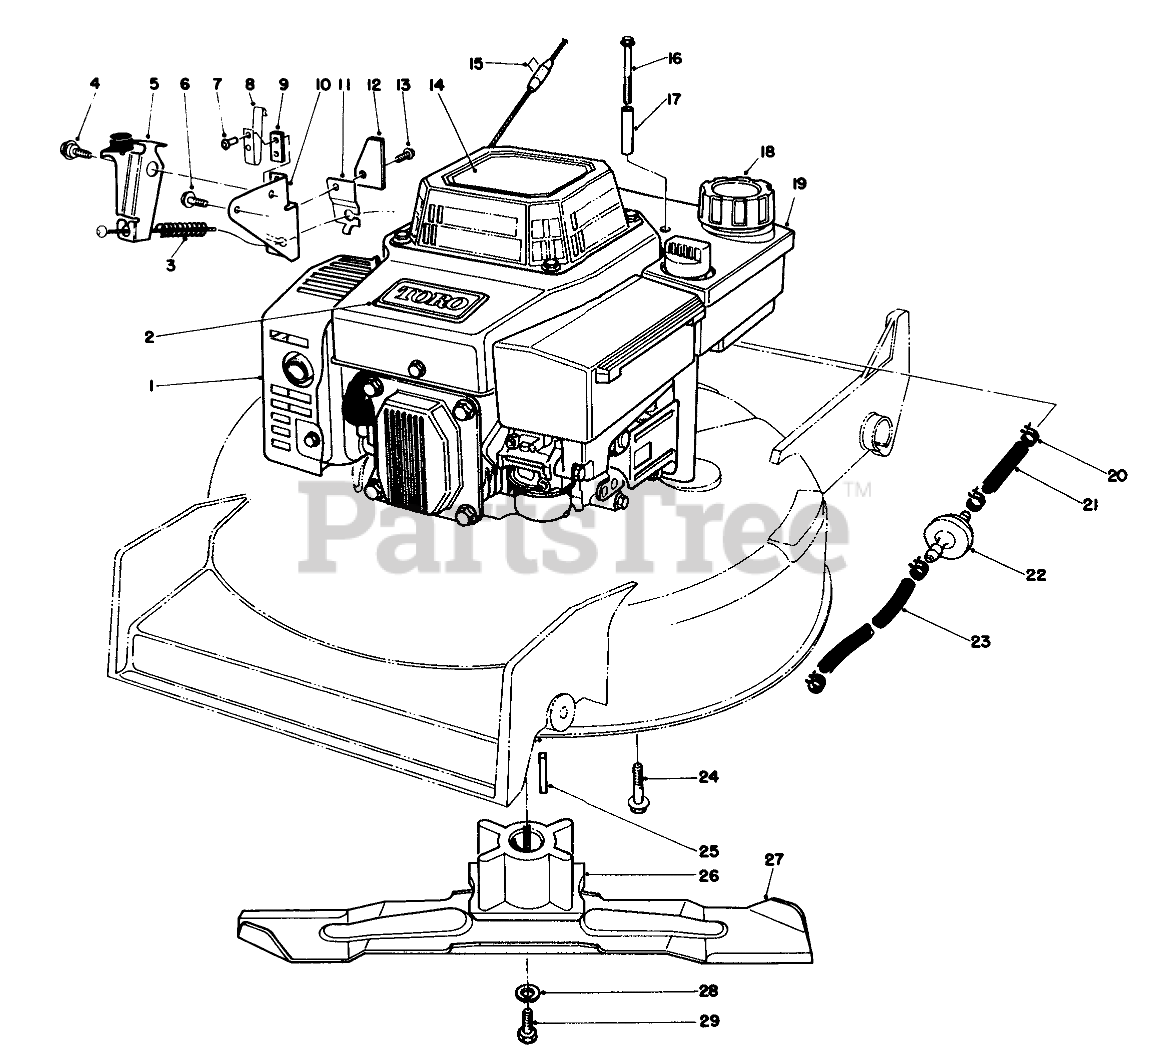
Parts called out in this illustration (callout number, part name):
1	Engine
2	TORO LOGO PLT
3	COMPRESSION SPRING
4	Screw-Shoulder
5	BRAKE PLATE ASM
6	THO FORM SCREW M6 X 1
7	RIVET-PLASTIC
8	Strap-Ground
9	Strap-Insulation
10	Plate-Mounting
11	CABLE CLAMP
12	STOP-GROUND STRAP
13	SCREW
14	OHV RECOIL DECAL
15	STAPLE
16	THRD FORMING SCREW
17	TUBULAR SPACER
18	GAS CAP ASM
19	TANK ASM
20	CLAMP-FUEL LINE
21	LINE-GAS
22	FILTER-FUEL
23	HOSE-FUEL
24	SCREW-HWHTF
25	KEY-SQUARE
26	Retainer Blade
27	BLADE-21in
28	WASHER-LOCK
29	SCREW-BLADE
